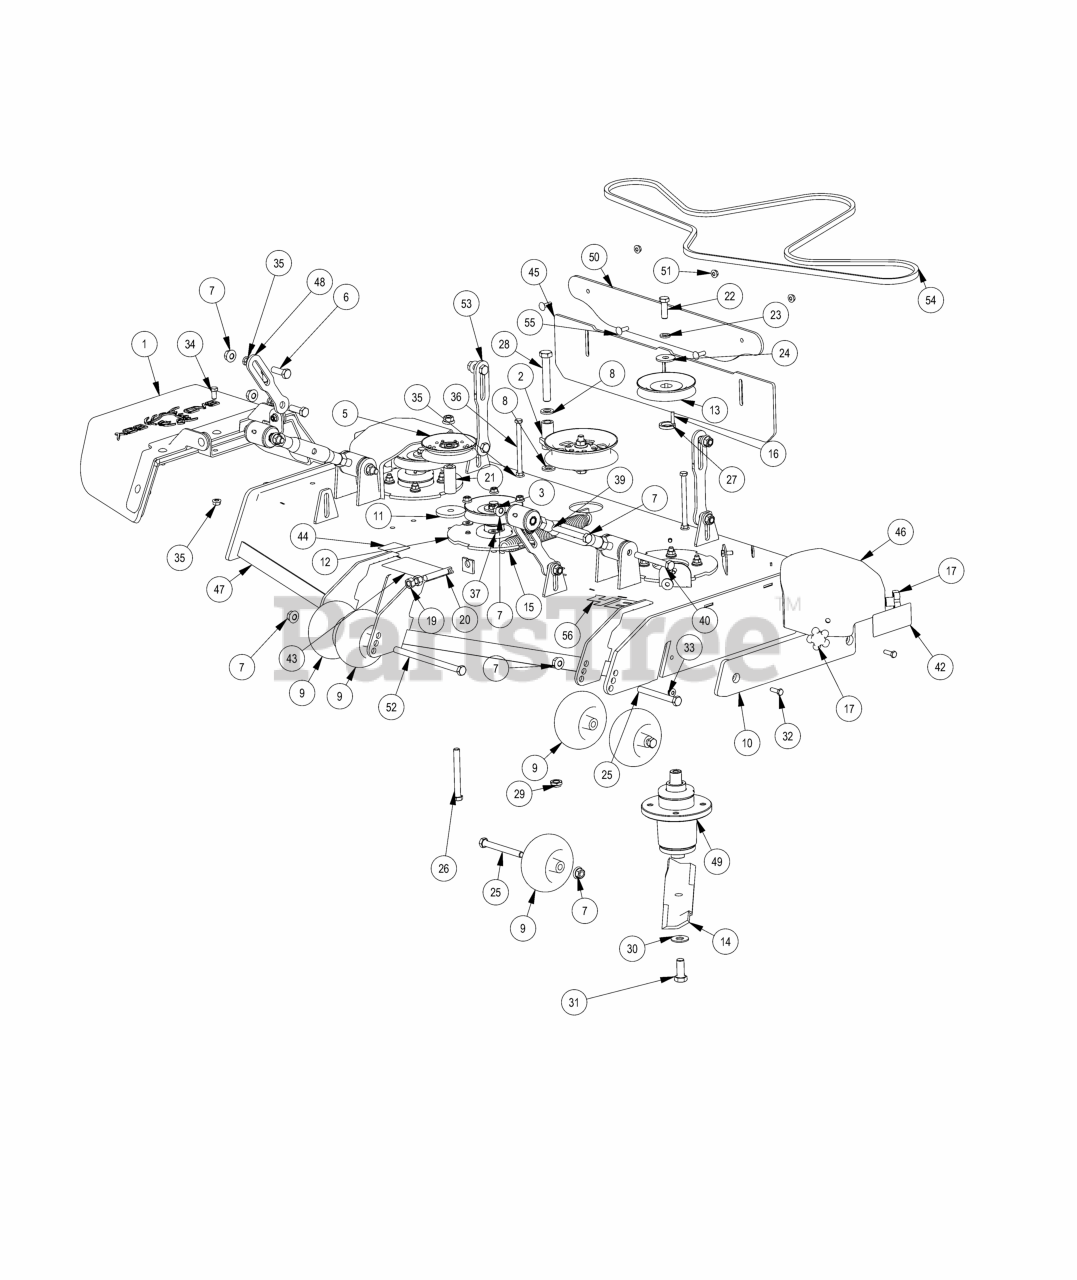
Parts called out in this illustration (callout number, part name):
1	2019 Outlaw Gen2 Chute Assembly
2	2019 Revolt Deck Idler Assembly
3	3/8-16 NYLON INSERT FLANGE LOCKNUT (GR.F) ZINC
4	5/16-24 X 1/4 SOCKET SET SCREW (CUP PT) PLAIN
5	4 3/4 Idler Pulley - ABFI-76
6	1/2-13 X 1-1/2 HEX CAP SCREW (GR.5) ZINC
7	1/2-13 NYLON INSERT FLANGE LOCKNUT ZINC
8	.635 ID X 1.120 OD X .140 THICK FLAT WASHER NYLON
9	2019 Deck Wheel
10	REVISED TRIM BUMPER_20180226
11	MZ Deck Idler Spacer
12	Deck Spindle Support Plate
13	5" Spindle Deck Pulley
14	48" ZT/Mav/Compact Outlaw Blade with Fusion
15	2019 Outlaw Gen2 Deck Spring
16	1/4 X 1 SQ MACHINERY KEY 1018 STL PLN
17	5/16" Knob
18	.360 ID X .983 OD X .120 THICK FLAT WASHER NYLON BLACK
19	1/2-13 HEX NUT ZINC
20	All Thread
21	2019 Revolt Stationary Idle Spacer
22	1/2-20 X 1-1/2 HEX CAP SCREW (GR.5) ZINC
23	1/2 SPLIT LOCKWASHER (GR.8) ZINC/YELLOW
24	1/2 BELLEVILLE WASHER (1-5/8 OD X .140 THK) ZINC
25	1/2-13 X 4-1/2 HEX CAP SCREW (GR.5) ZINC
26	1/2-13 X 4-1/4 HEX CAP SCREW (GR.5) ZINC
27	1.02 ID X 1.38 OD X .250 THK SPACER ZINC
28	5/8-11 X 4 HEX CAP SCREW (GR.8) ZINC YELLOW
29	5/8-11 NYLON INSERT JAM LOCKNUT ZINC
30	5/8 USS FLAT WASHER (1-3/4" OD) GR.8 ZINC YELLOW
31	5/8-18 X 1-1/2 HEX CAP SCREW (GR.8) ZINC YELLOW
32	5/16-18 X 1 HEX CAP SCREW (GR.5) ZINC
33	5/16-18 NYLON INSERT FLANGE LOCKNUT ZINC
34	3/8-16 X 3/4 HEX CAP SCREW (GR.5) ZINC
35	3/8-16 HEX SERRATED FLANGE NUT HARD/ZINC
36	3/8-16 X 5-1/2 HEX CAP SCREW (GR.5) ZINC
37	5/16 USS FLAT WASHER (7/8 OD) ZINC
38	3/8-16 X 1-3/4 HEX C/S (GR.5) ZC
39	Turnbuckle
40	1/2-13 X 4 HEX CAP SCREW (GR.8) ZINC YELLOW
42	Danger Decal-Spindle/Discharge
43	2019 Revolt Deck Belt Route Decal
44	Deck Impact Patent Decal 9591803
45	2023 MZ Stripping Kit Rubber
46	2023 Revolt pulley cover
47	2023 48'' DECK
48	Deck Hangar
49	OUTLAW SPINDLE ASSEMBLY
50	Striping Kit Plate
51	5/16-18 HEX SERRATED FLANGE NUT HARD/ZINC
52	1/2-13 X 8 HEX CAP SCREW GR 5 ZINC
53	2023 Stand-On Rear Deck HangerV2
55	5/16-18 X 1 CARRIAGE BOLT (GR.8) ZINC
56	48" Deck Decal
